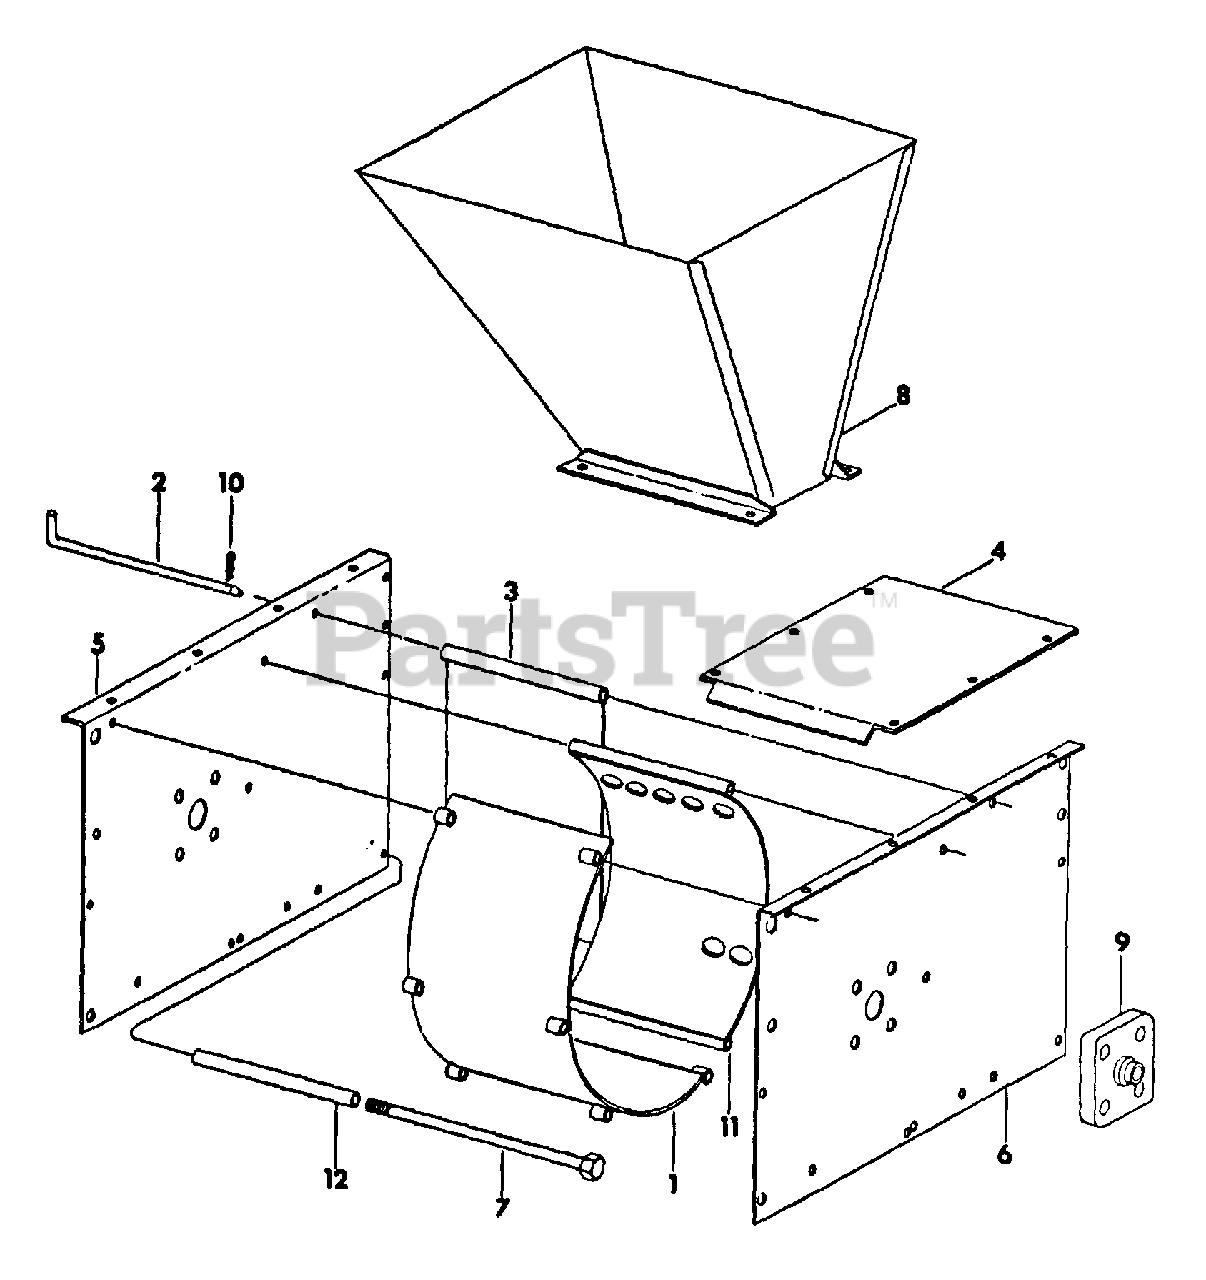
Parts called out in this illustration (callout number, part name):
1	SCROLL
2	ROD, SCREEN & BAFFLE
3	PLATE, BAFFLE
4	PLATE TOP
5	PLATE, SIDE LH
6	PLATE, SIDE RH
7	ROD, TIE
8	HOPPER
9	BEARING FLANGE
10	PIN, QUICK ATTACHABLE
11	SCREEN, 1 IN. PERFORATIONS
12	SPACER
